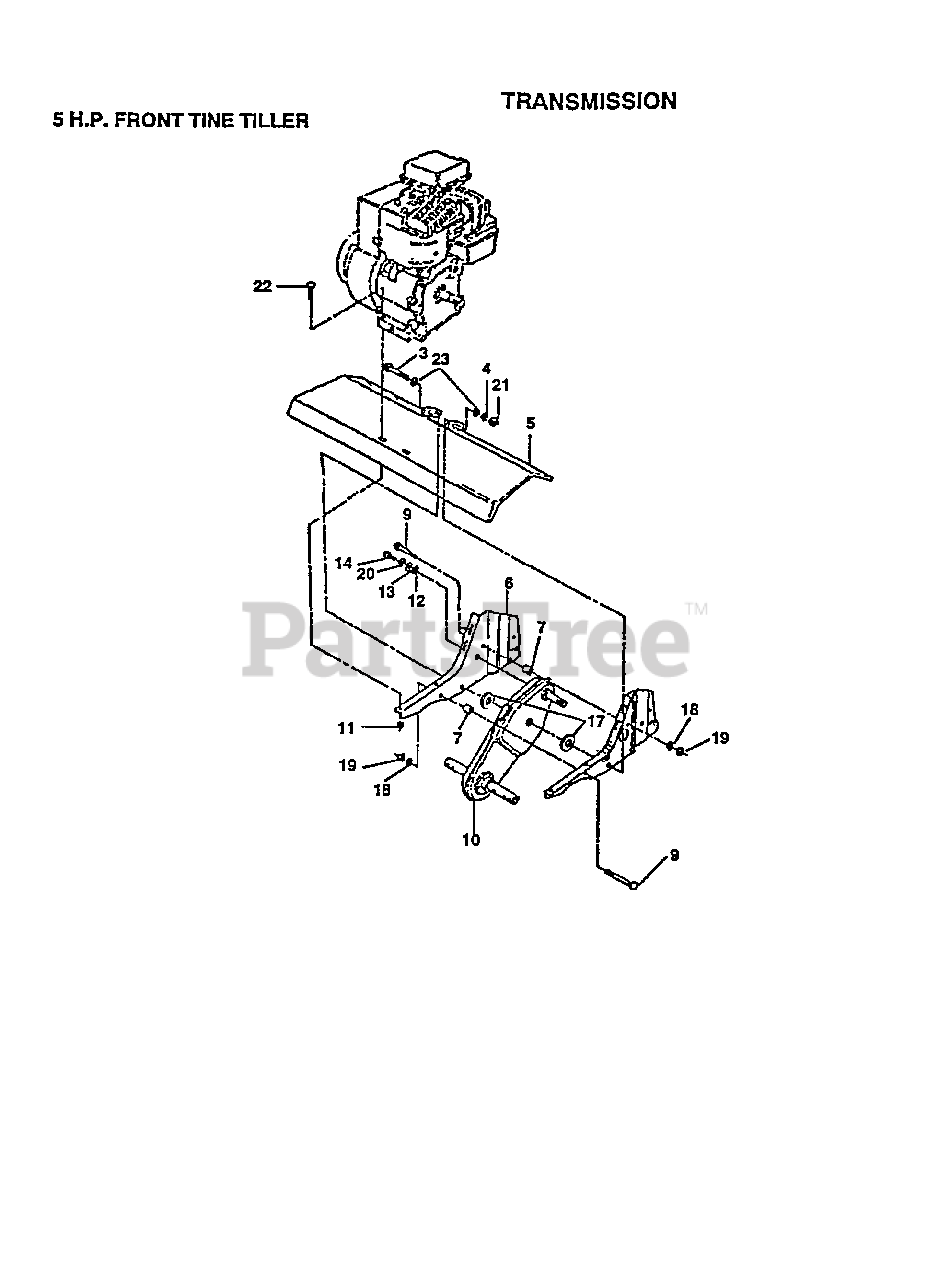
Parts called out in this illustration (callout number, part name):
3	BOLT.3/8-24X3.75
4	LOCKWASHER
7	SPLIT SPACER RT
8	BRACKET.ENG.LH.
12	WASHER
13	WASHER
14	BOLT
18	LOCKWASHER
19	NUT.HEX.5/16-18
20	LOCKWASHER
21	GRIPCO NUT
22	BOLT.HEX.5/16-1.5
23	WASHER
